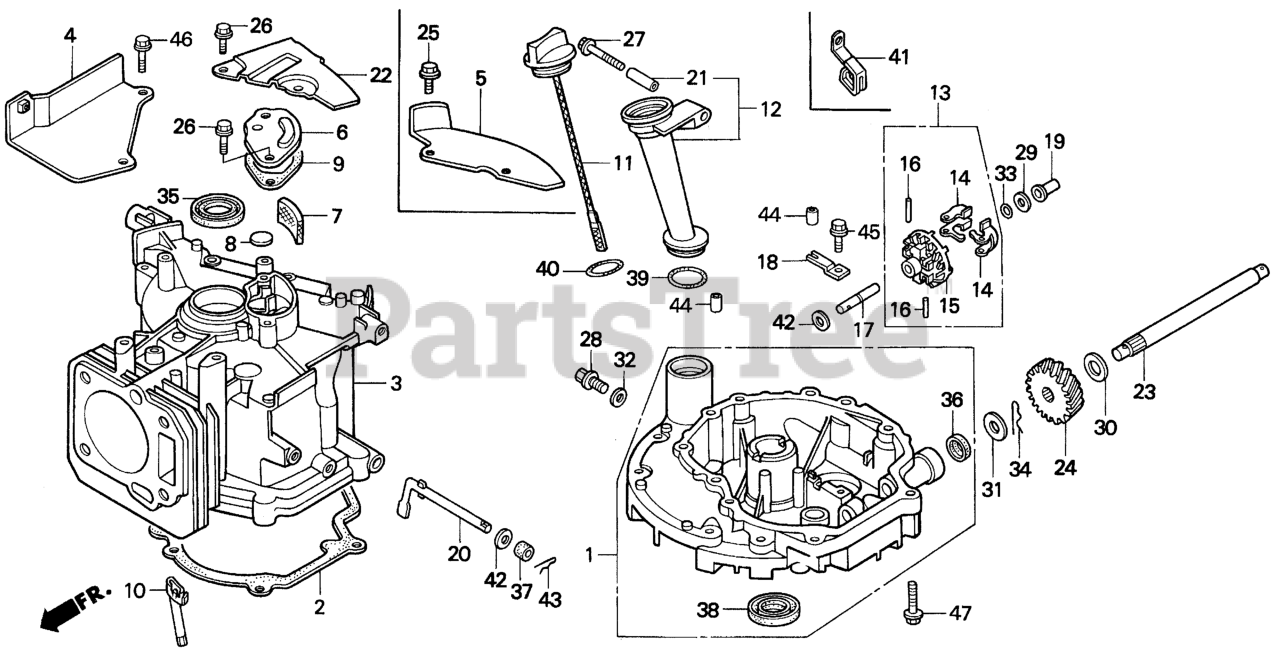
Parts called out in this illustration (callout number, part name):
1	PAN KIT, OIL
2	GASKET, OIL PAN (HPE)
3	CYLINDER
4	PLATE, GUIDE
6	CAP, BREATHER CHAMBER
7	FILTER, BREATHER
8	VALVE, BREATHER
9	GASKET, BREATHER CHAMBER
10	PIPE, OIL DEFENSE
11	GAUGE, OIL LEVEL Use up to Engine SN 1257294.
12	EXTENSION, OIL FILLER (106MM)
13	GOVERNOR ASSY.
14	WEIGHT, GOVERNOR
15	HOLDER, GOVERNOR WEIGHT
16	PIN, GOVERNOR WEIGHT
17	SHAFT, GOVERNOR HOLDER
18	PLATE, GOVERNOR SHAFT HOLDER
19	SLIDER, GOVERNOR
20	SHAFT, GOVERNOR ARM
21	COLLAR, EXTENSION Use up to Engine SN 1257294.
22	STAY, TANK
23	SHAFT, DRIVE
24	GEAR, DRIVEN (22T)
26	BOLT, FLANGE (6X14)
27	BOLT, FLANGE (6X32)
28	BOLT, DRAIN PLUG
29	WASHER, THRUST (6MM)
30	WASHER, THRUST (12MM)
31	WASHER (10X21)
32	WASHER, DRAIN PLUG (10.2MM)
33	CLIP, GOVERNOR HOLDER
34	PIN, LOCK (2.0)
35	OIL SEAL (22X35X6)
36	OIL SEAL (12X20X5) (ARAI)
37	OIL SEAL (6X11X4)
38	OIL SEAL (25X38X7) (ARAI)
39	O-RING (22.5X2.2) Use from Engine SN 1257295.
40	O-RING (26X2.7)
42	WASHER, PLAIN (6MM)
43	PIN, LOCK (8MM)
44	PIN A, DOWEL (8X14)
45	BOLT, FLANGE (6X12) Use from Engine SN 2086984.
46	BOLT, FLANGE (6X20)
47	BOLT, FLANGE (6X28)
NI	GOVERNOR KIT
